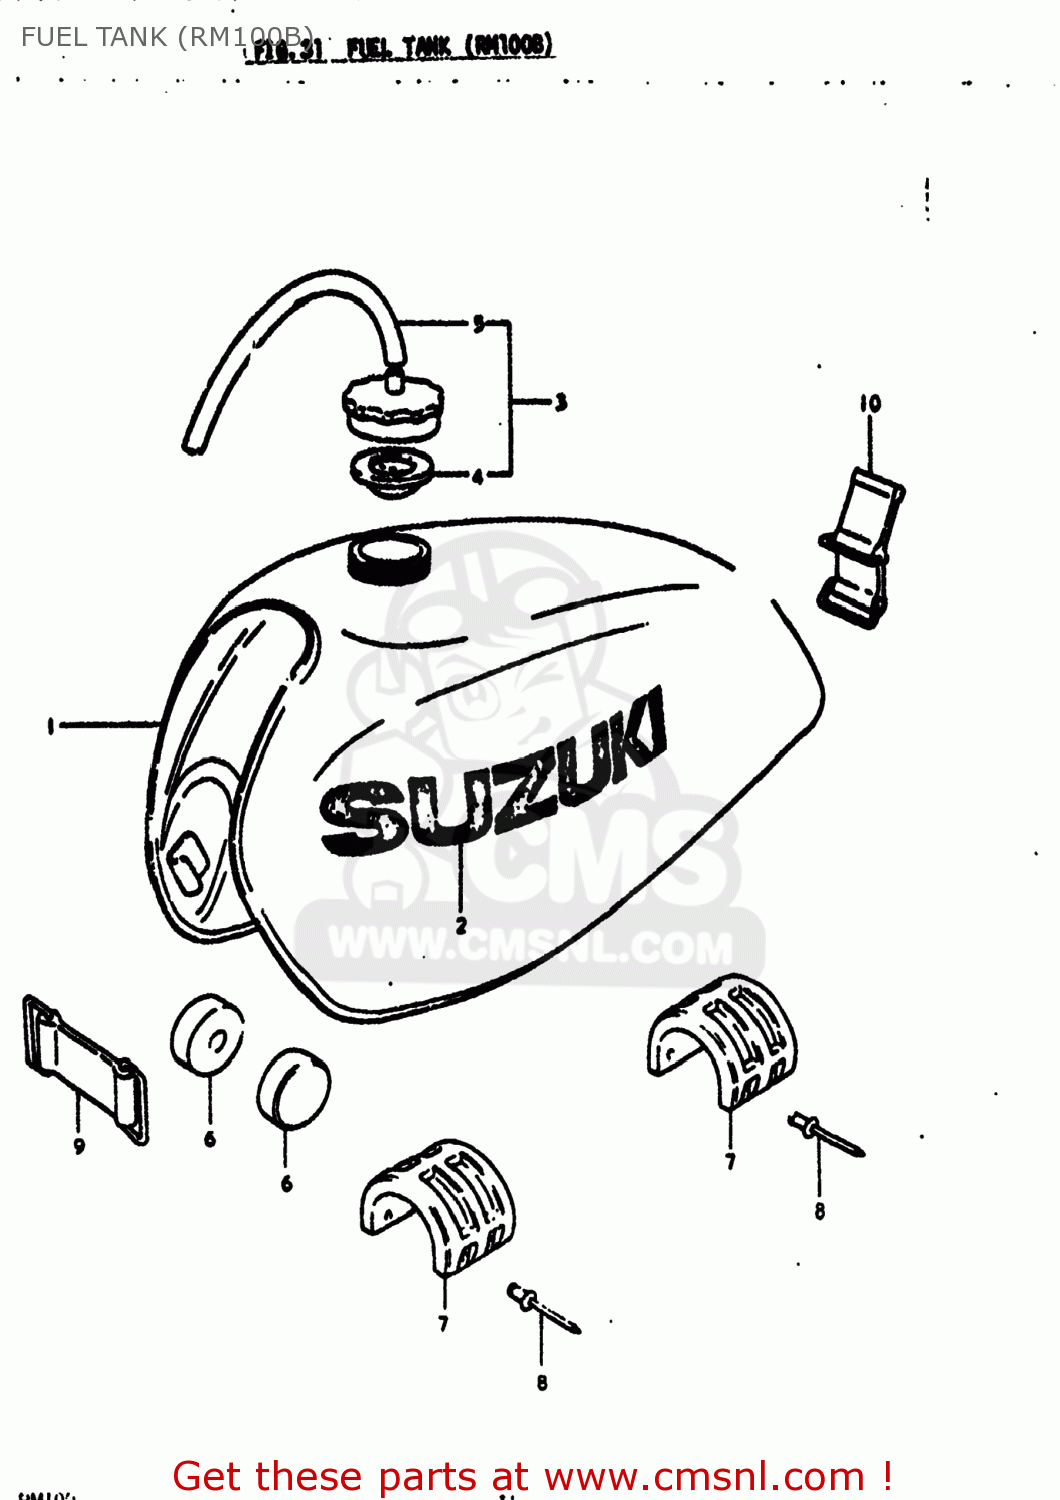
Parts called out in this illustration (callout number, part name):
1	TANK ASSEMBLY,FUEL
2	EMBLEM
3	CAP ASSY,FUEL TANK FILLER
4	GASKET,FUEL TANK CAP (NAS)
5	HOSE
6	CUSHION
7	CUSHION,FUEL TANK,CENTER
8	RIVET
9	BAND
10	BAND
